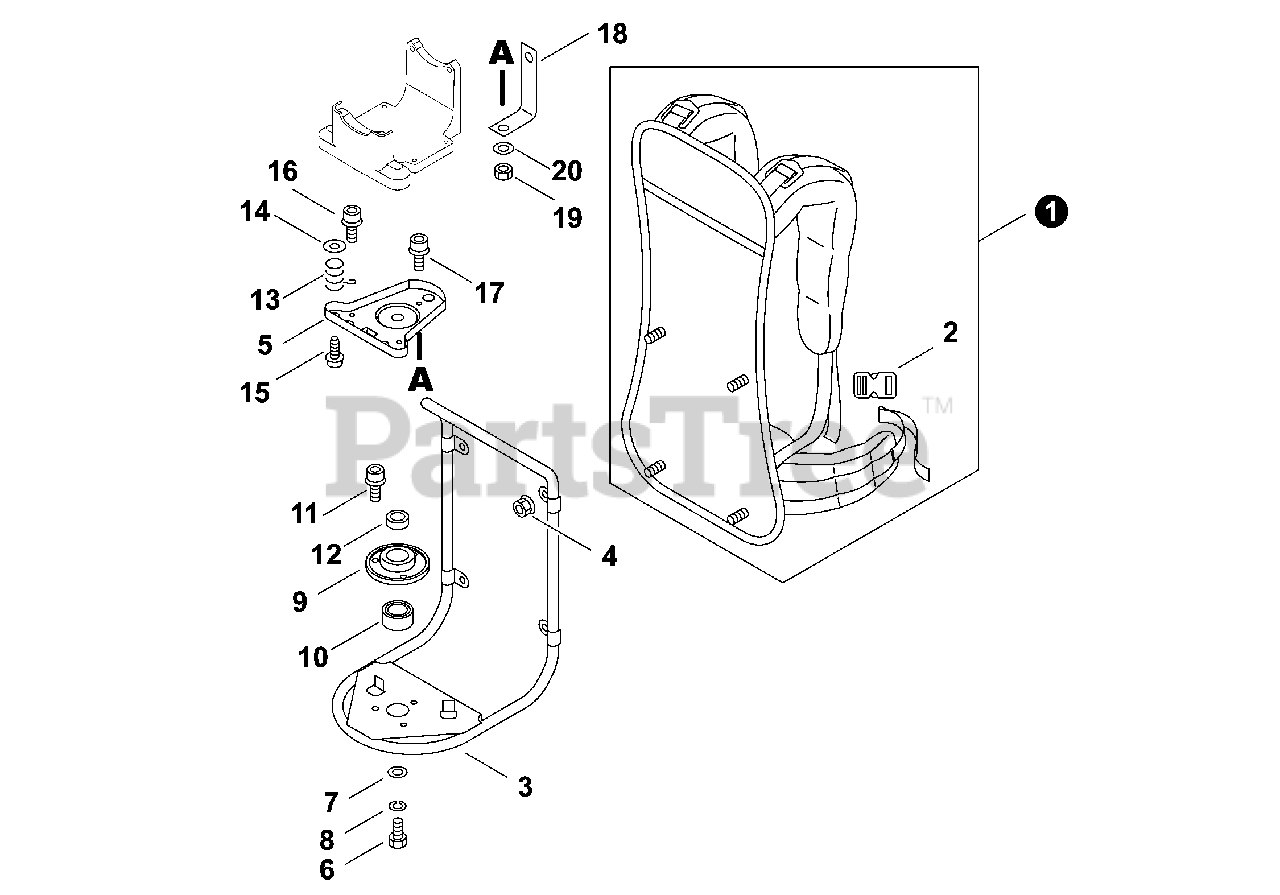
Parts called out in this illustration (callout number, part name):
1	HARNESS, BACKPACK
3	FRAME, BACKPACK
4	NUT, FLANGE M5
5	PLATE
7	WASHER 10.5×18×1.6
8	WASHER, SPRING 10
9	HOLDER, BEARING
10	BEARING, BALL 6202ZZ
11	BOLT, FLANGE
12	COLLAR
13	SPRING, COMPRESSION
14	WASHER 5.2×16×1.0
15	BOLT 5×20
16	BOLT 5×12
17	BOLT 5×16
18	STOPPER
20	WASHER, FLAT 5.5×10×0.8
